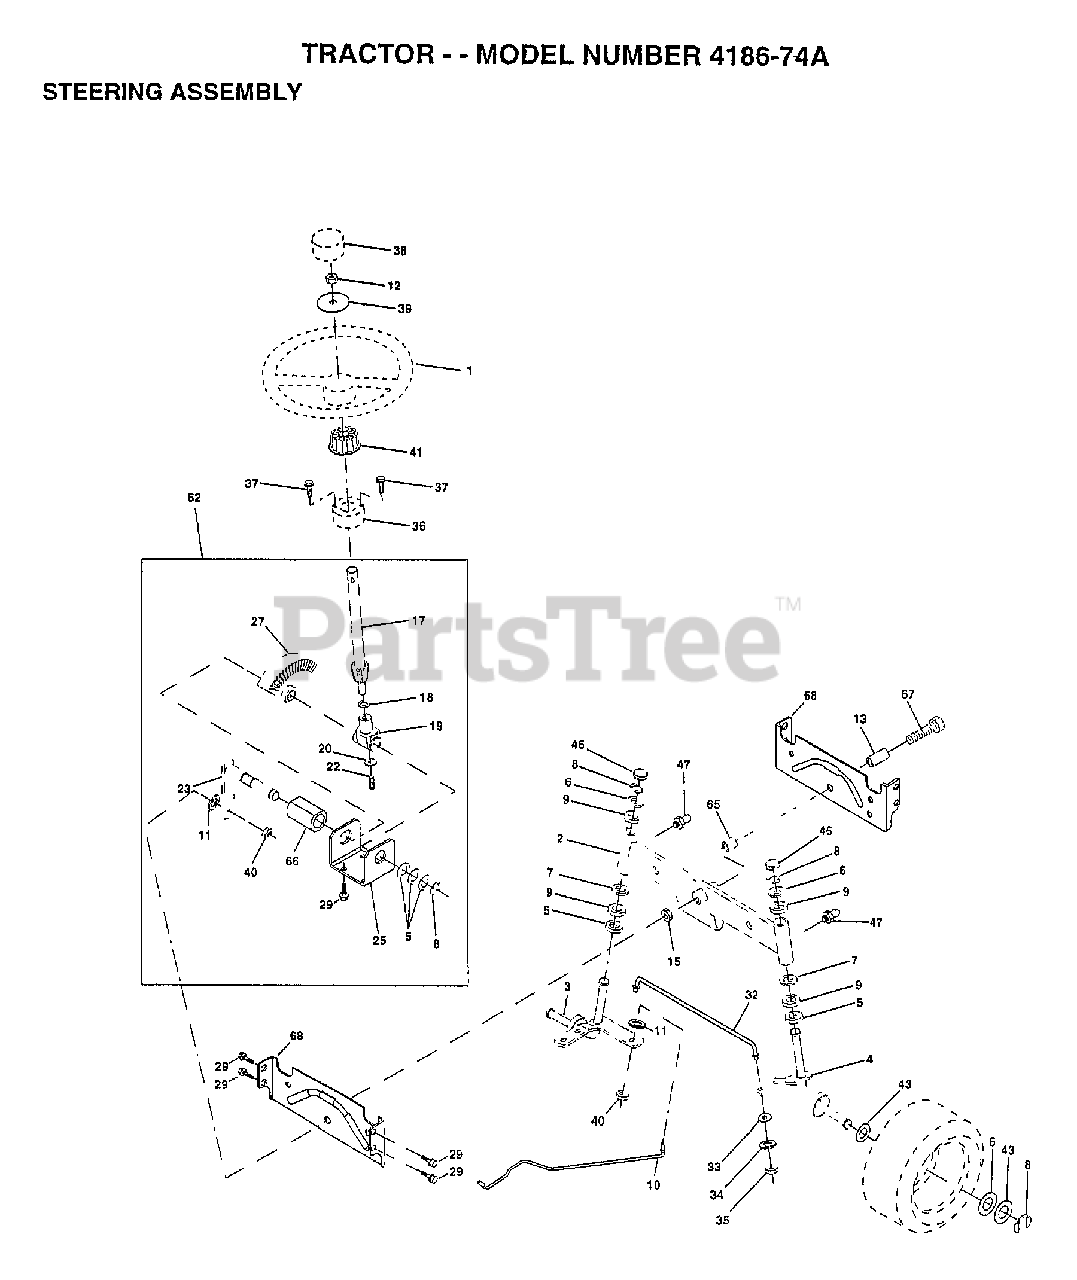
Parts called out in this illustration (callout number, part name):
2	AXLE ASM
3	SPINDLE.ASM.LH
4	"SPINDLE ASM,RH"
5	WASHER .T
6	WASHER
7	WASHER
8	RING
9	COL. SRTG. BEAR.
10	DRAGLINK-STAMPED
11	LOCKWASHER
13	BEARING AXLE
15	"NUT-LOC,FLANGE LT"
17	STEERING SHAFT
18	THRUST WASHER
19	SUPPORT.SHAFT
22	SCREW HEX SOC1/4-
25	BRKT-STEERING
27	GEAR SECTOR
29	SCREW
32	ROD.TIE.19.75
33	WASHER M
34	LOCKWASHER
35	NUT.LOCK.5/16-24
36	BUSHING.STRG.3/4
37	"SCREW-TT,10-32 FL"
38	"INSERT,STR WHEEL"
39	WASHER
40	GRIPCO NUT
41	ADAPTER LT
43	WASHER
46	CAP
47	ZERK M
56	WASHER
62	STEERING KIT
65	SPACER AXLE
66	"BEARING-ARM,PITMA"
67	BOLT
68	BRACE AXLE
